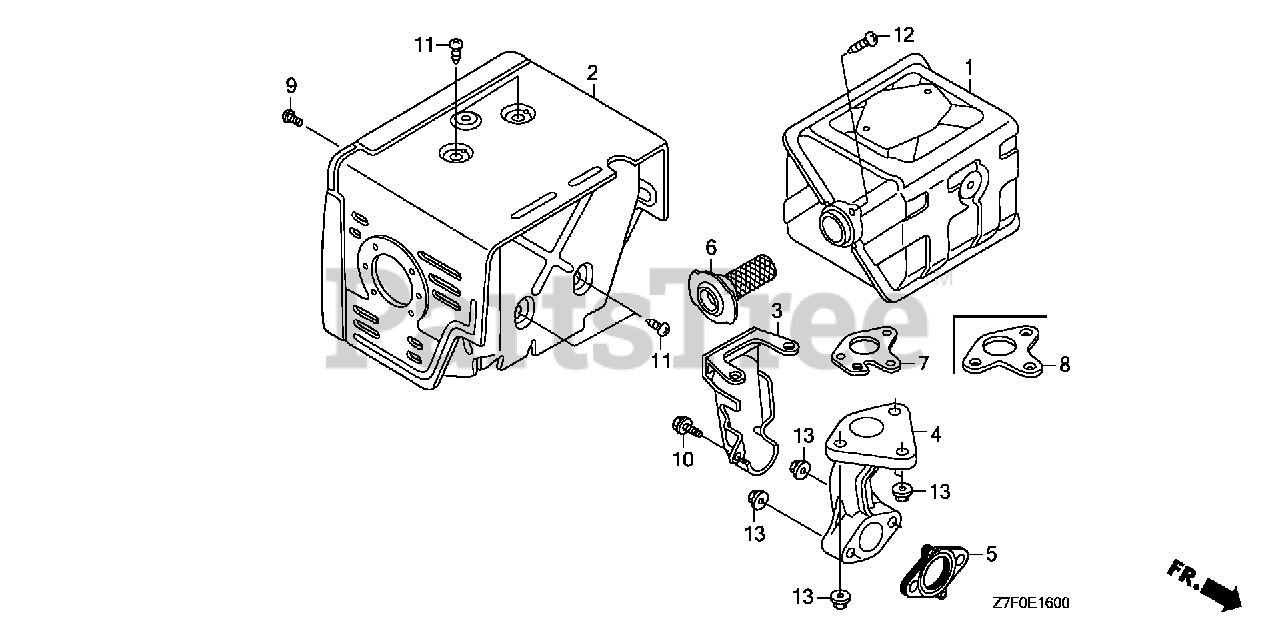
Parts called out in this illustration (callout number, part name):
1	MUFFLER (100DB)
2	PROTECTOR, MUFFLER
5	GASKET, EX. PIPE
6	ARRESTER, SPARK
7	GASKET, MUFFLER (ARRESTER) (NIPPON LEAKLESS)
8	GASKET, MUFFLER (NIPPON LEAKLESS)
8	GASKET, MUFFLER (THAI LEAKLESS)
9	SCREW, TAPPING (6X10)
11	SCREW, TAPPING (5X8)
12	SCREW, TAPPING (4X6)
13	NUT, FLANGE (8MM)
